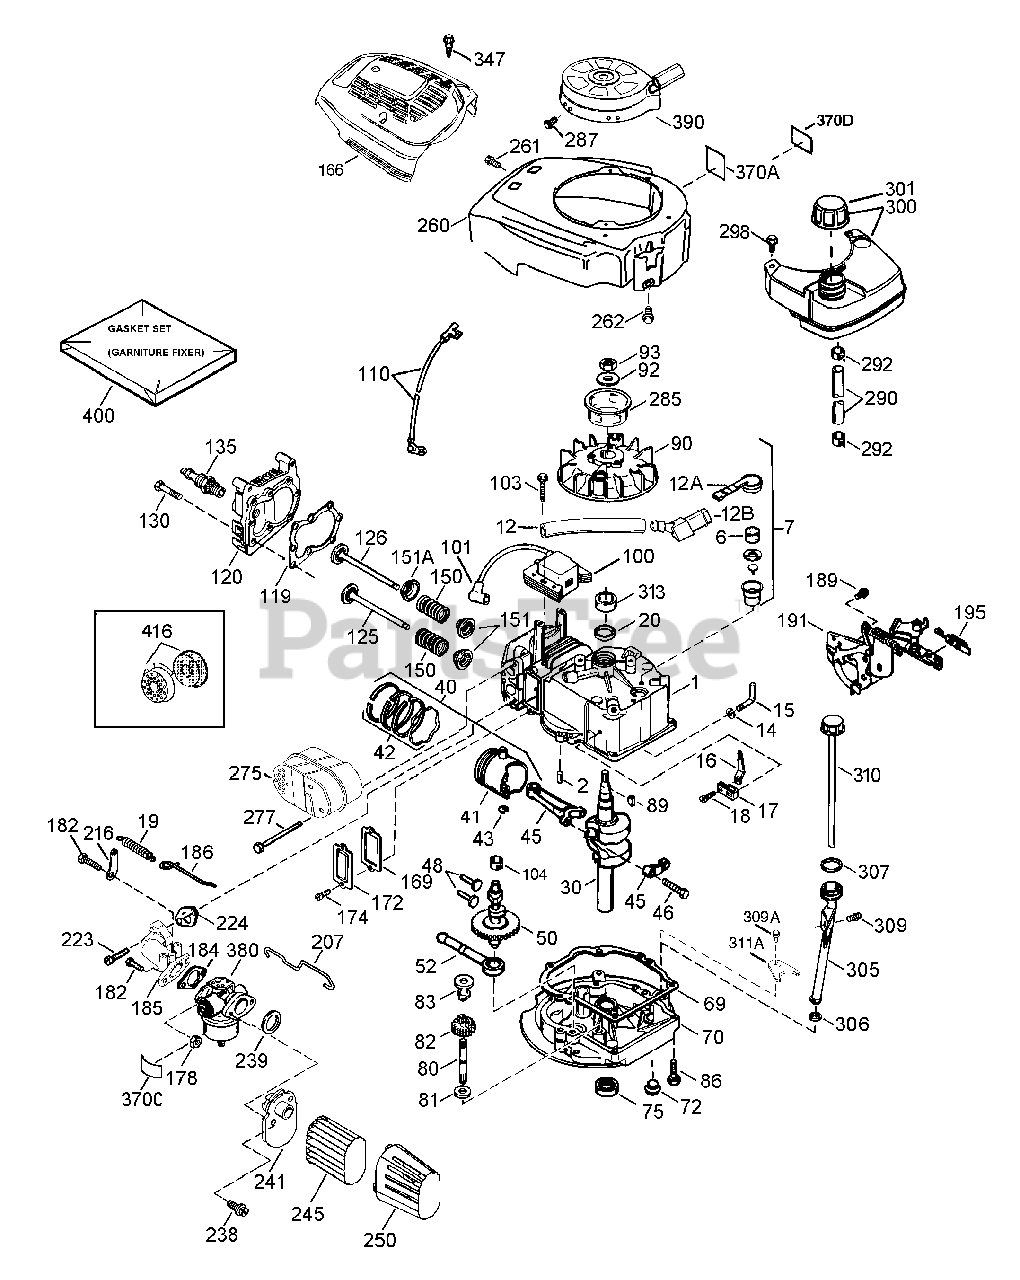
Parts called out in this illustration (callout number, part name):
1	Cylinder(Incl. REF. #2, 20 and 150)
2	Pin-Dowel
6	Element-Breather
7	Breather ASM (Incl. REF. #6 AND 12A)
12	Tube-Breather
12A	Breather Cover And Tube (Incl. REF. #12B)
12B	Elbow-Breather Tube
14	Washer
15	Governor Rod (Incl. REF. #14)
16	Lever-Governor
17	Lever Clamp-Governor
18	Screw, T-15, 8-32 x 19/64in
19	Spring-Extension
20	Seal-Oil
30	Crankshaft
40	Piston, Pin and Ring Set (Std.)
41	Piston and Pin ASM (Std.) (Incl. REF. #43)
42	Ring Set (Std.)
43	Piston Pin Retaining Ring
45	Connecting Rod ASM (Incl. REF. #46)
46	Bolt-Connecting Rod
48	Valve-Lifter
50	Camshaft (Exhaust MCR) (Incl. REF. #104)
52	Oil Pump ASM.
69	Gasket-Mounting Flange
70	Mounting Flange (Incl. REF. #72-83, 306, 309A and 311A)
72	Plug-Oil Drain
75	Seal-Oil
80	Shaft-Governor
81	Washer
82	Governor Gear ASM (Incl. REF. # 81)
83	Spool-Governor
86	Screw, 1/4-20 x 1-1/4in
89	Key-Flywheel
90	Flywheel
92	Washer-Belleville
93	Nut-Flywheel
100	Ignition-Solid State
101	Cover-Spark Plug
103	Screw, T-15, 10-24 x 15/16in
104	Bushing-Cam
110	Wire-Ground
119	Gasket-Cylinder Head
120	Cylinder Head
125	Exhaust Valve (1/32" OS) (Incl. REF. #151)
125	Exhaust Valve (Std.) (Incl. REF. #151)
126	Intake Valve (Std.) (Incl. REF. #151and 151A)
130	Screw, 5/16-18 x 1-7/16in
135	Resistor Spark Plug (RJ19LM)
150	Spring-Valve
151	Cap-Valve Spring
151A	Seal-Intake Valve
166	Engine Shroud (Green)
169	Gasket-Valve Cover
172	Cover-Valve
174	Screw, 10-24 x 9/16in
178	Nut & Lock Washer, 1/4-28
182	Screw, 1/4-28 x 7/8in
184	Carburetor To Intake Pipe Gasket
185	Pipe-Intake
186	Link-Governor
189	Screw, 1/4-20 x 3/8in
191	S.E. Brake Bracket (Incl. REF. #195)
195	Terminal
207	Link-Throttle
216	Lever-R.P.M. Adjusting
223	Screw, 1/4-20 x 1in
224	Gasket-Intake Pipe
238	Screw, 10-32 x 49/64in
239	Gasket-Air Cleaner
241	Collar-Air Cleaner
245	Filter-Air Cleaner
250	Cover-Air Cleaner
260	Housing-Blower
261	Screw, 10-24 x 9/16in
262	Screw, 1/4-20 x 1/2in
275	Muffler
277	Screw, 1/4-20 x 2-9/32in
285	Cup-Starter
287	Screw, 8-32 x 21/64in
290	Line-Fuel
292	Clamp-Line, Fuel
298	Screw
